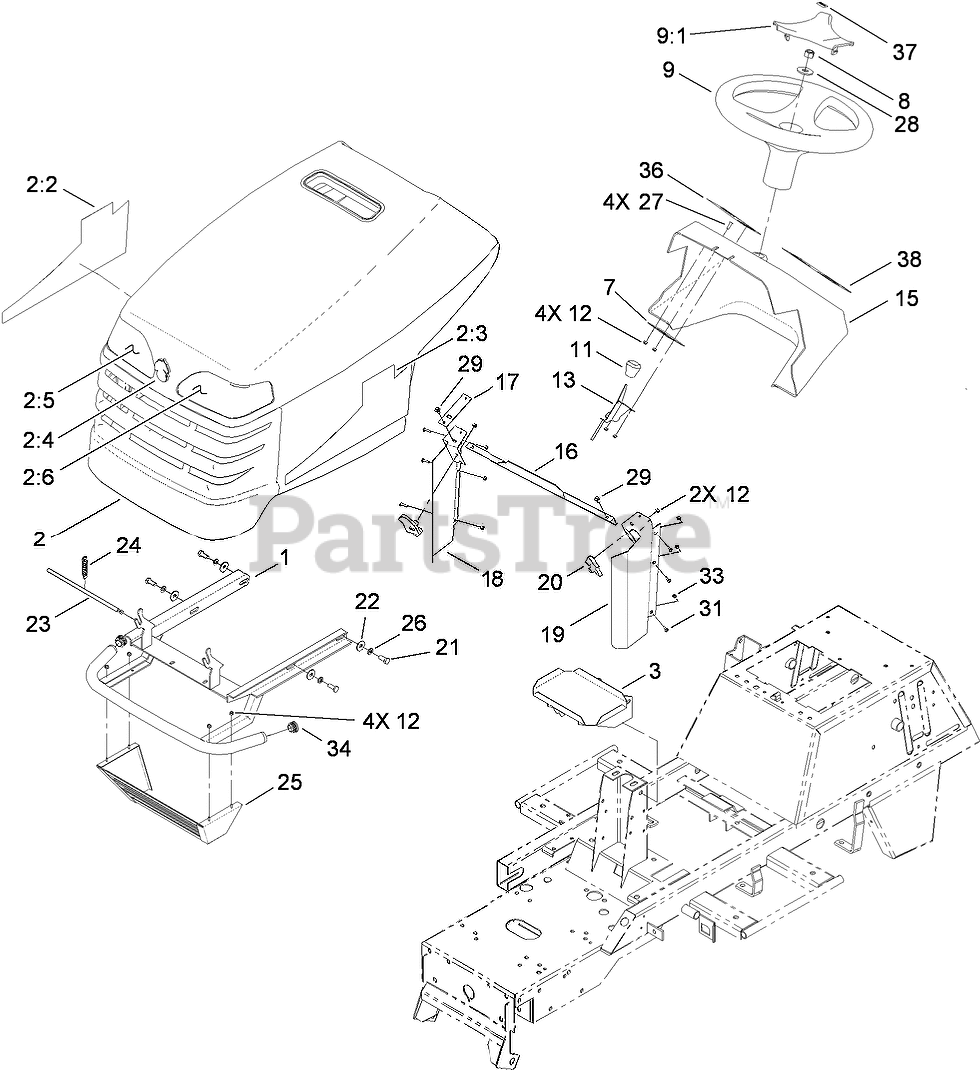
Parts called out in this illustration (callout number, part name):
1	SUPPORT-BUMPER
2	HOOD ASM
2:2	DECAL-HOOD, RH
2:3	DECAL-HOOD, LH
2:4	EMBLEM
2:5	LENS-HEADLAMP, RH
2:6	LENS-HEADLAMP, LH
3	TRAY-BATTERY
8	NUT-LOCK
9	WHEEL-STEERING
9:1	COVER-WHEEL, STEERING
12	NUT-LOCK
13	CABLE-THROTTLE and CHOKE
15	PANEL-DASH
17	BRACKET
18	PANEL-RIGHT
19	PANEL-LEFT
20	LATCH-HOOD
21	SCREW-HH
22	WASHER-PLAIN
23	BAR-SAFETY
24	SPRING-HOOD
25	GUARD-MUFFLER
26	WASHER-LOCK
28	Washer
33	NUT-HEX
34	PLUG-END, TUBE
36	DECAL-CHOKE/THROTTLE/KEY
37	DECAL
38	DECAL-PTO
